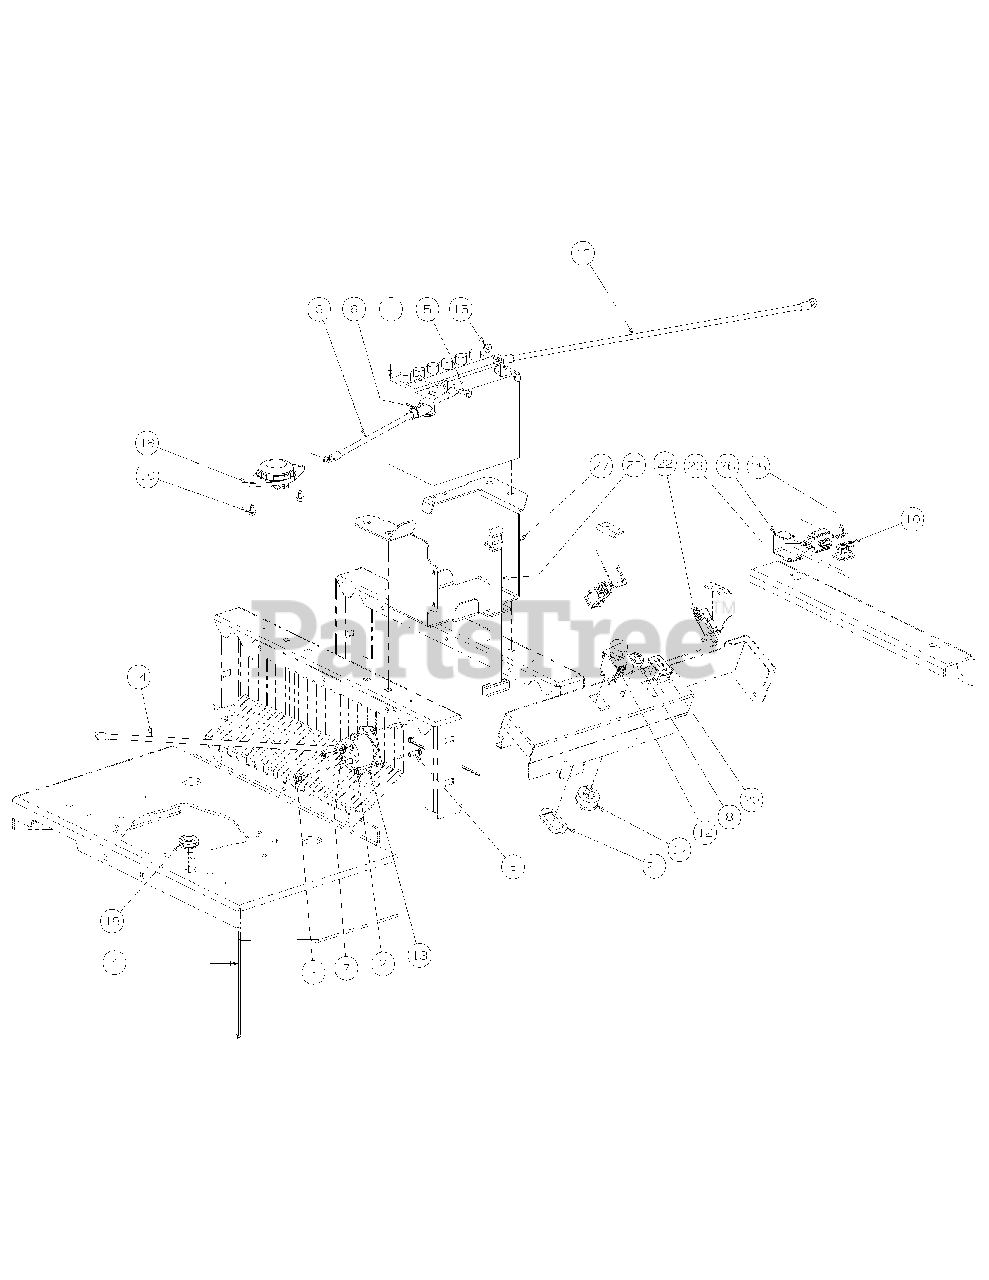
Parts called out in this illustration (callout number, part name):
1	Battery
2	Lock Nut, Nylon Insert, 1/4-20
3	Nut, 5/16-18, Nylock
4	Tie, Cable, 3/16 x .05 x 7.4"
5	Screw, Hex, Cap, 1/4-20 x .75
6	Boot, 1" OD Rubber Battery-PST, Red
7	Lock Nut, Nylon Insert, 10-32
8	Nut, W/Cap, 5/8-32 Ignition
9	Battery Cable, 15" Red
10	Screw, TT, 1/4-20 x .5, Hex Index Washer
12	Switch, Electric, PTO
13	Solenoid
14	Battery Cable, 24" Red
15	Nut, 1/4-20, Hex Flange Lock Nut
16	Switch, Seat N/C
17	Switch, Ignition, 6 Pin
18	Grommet, .75 ID
19	Cable, Battery Black, 28"
20	Meter, Hour
21	Bracket, PTO Switch Retainer
22	Switch, Safety
23	Switch, Plunger
25	Switch Bracket Mount
26	Switch Clamp
27	Mount Bracket, Battery
28	Strap, Battery
